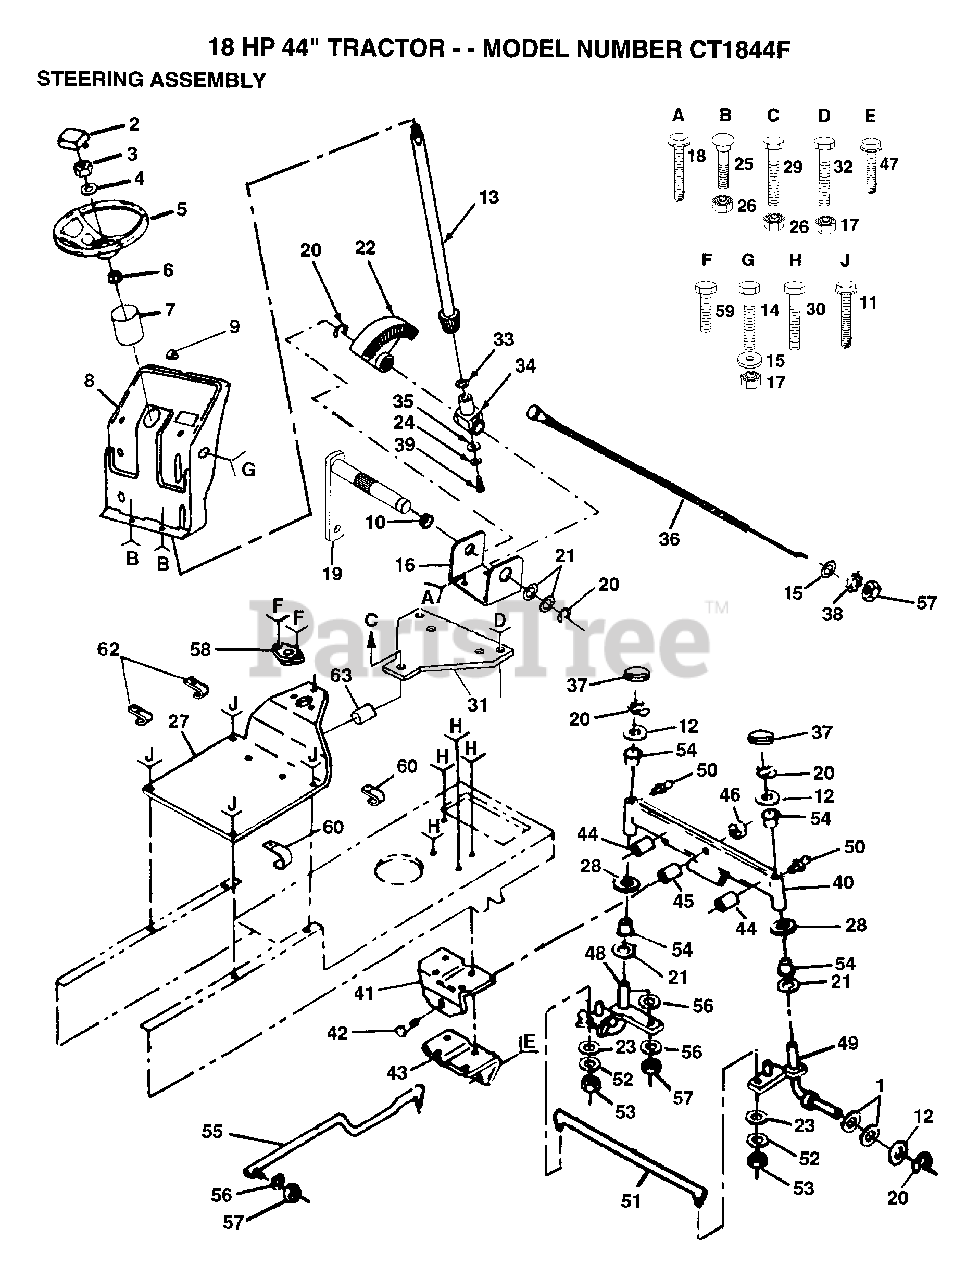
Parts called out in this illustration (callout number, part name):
1	WASHER
2	ST WHL INSERT CAP
4	WASHER
6	ADAPTER LT
7	SLEEVE LTV
9	PLUG-DASH T
10	NYLINER T
11	SCREW LT
12	WASHER
13	SHAFT&GEAR STR T
15	WASHER
16	"BRKT,STEERING"
18	SCREW
20	RING
21	WASHER .T
22	GEAR SECTOR
23	WASHER M
24	LOCKWASHER
25	SCREW
27	SADDLE.YT.GOOSE N
28	WASHER
29	BOLT
30	SCREW SPECIAL
33	THRUST WASHER
34	SUPPORT.SHAFT
36	CHOKE CONTROL
37	CAP
38	LOCKWASHER
39	"SCREW,SPECIAL"
40	FRONT AXLE
41	SUPPORT-SADDL T
42	BOLT LT
43	SUPPORT.SADDLE.FT
44	AXLE PIN
45	BEARING
46	"NUT-LOC,FLANGE LT"
47	SCREW LT
48	SPINDLE LH
49	SPINDLE RH
50	ZERK M
51	TIE ROD
52	LOCKWASHER
53	NUT.LOCK.5/16-24
54	COL. SRTG. BEAR.
56	LOCKWASHER
60	CLIP T
62	"CLIP,INSULATOR"
63	SPACER
